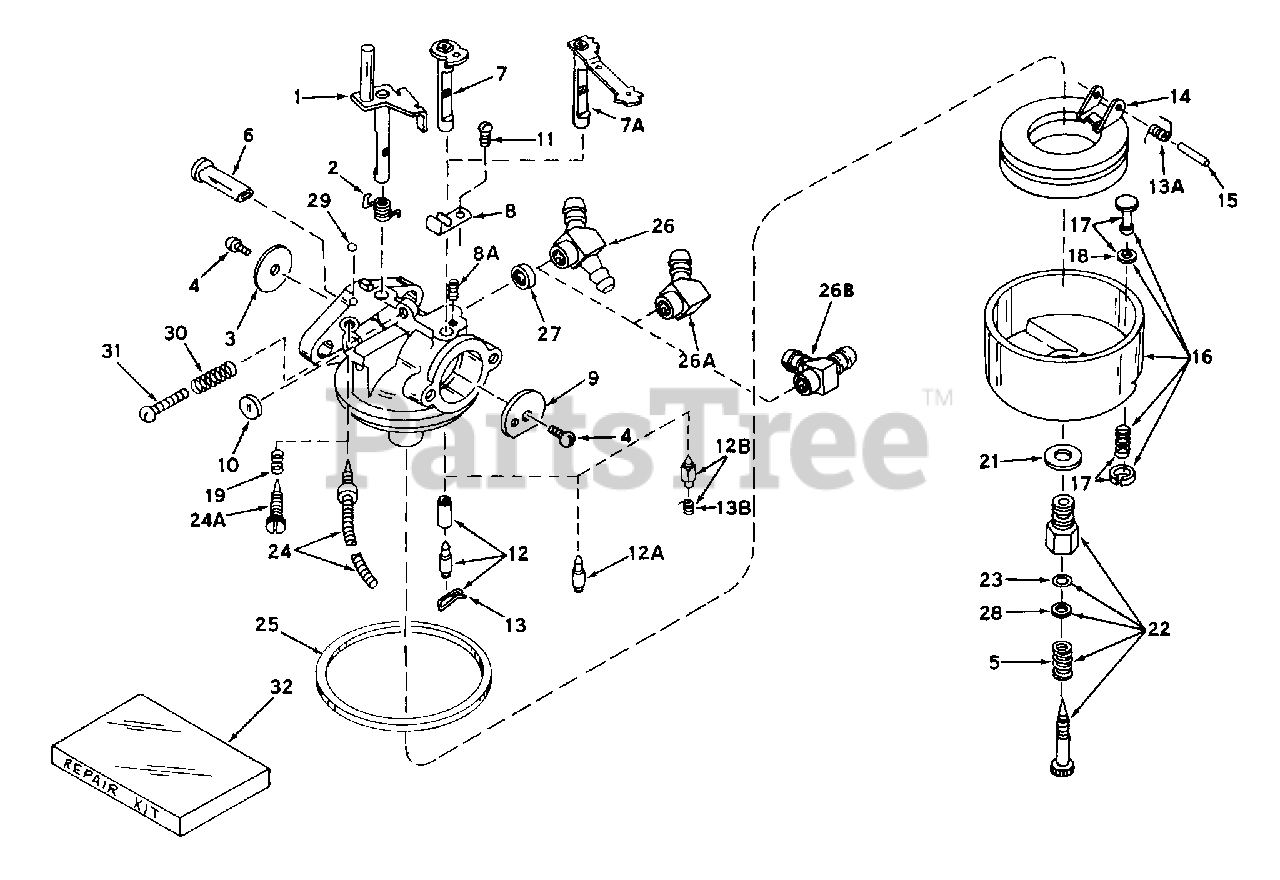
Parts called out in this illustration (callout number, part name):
1	"Shaft & Lever Assy., Throttle
2	Spring, Throttle return
3	Shutter, Throttle
4	Screw, Rd. hd., 4-40 x 3/16
5	Spring, Main adjustment screw
6	Element, Pump
7	Shaft & Lever Assy., Choke
8	Spring, Detent
9	Shutter, Choke
10	Plug, Welch
11	Screw, Rd. hd., 6-32 x 3/16
12B	Inlet Needle & Spring Assy.
14	Float, Carburetor
15	Shaft, Float
16	Bowl & Drain Assy., Float
17	Plunger Assy., Drain
18	Gasket, Drain plunger
21	Gasket, Bowl-to-body
22	Adjustment Screw Assy., Main
23	"O" Ring, Adjustment screw
24	Screw Assy., Idle
25	Gasket, Bowl-to-body
26	Fitting, Fuel inlet
27	Valve, Check
29	Shot, Lead
32	Repair Kit
